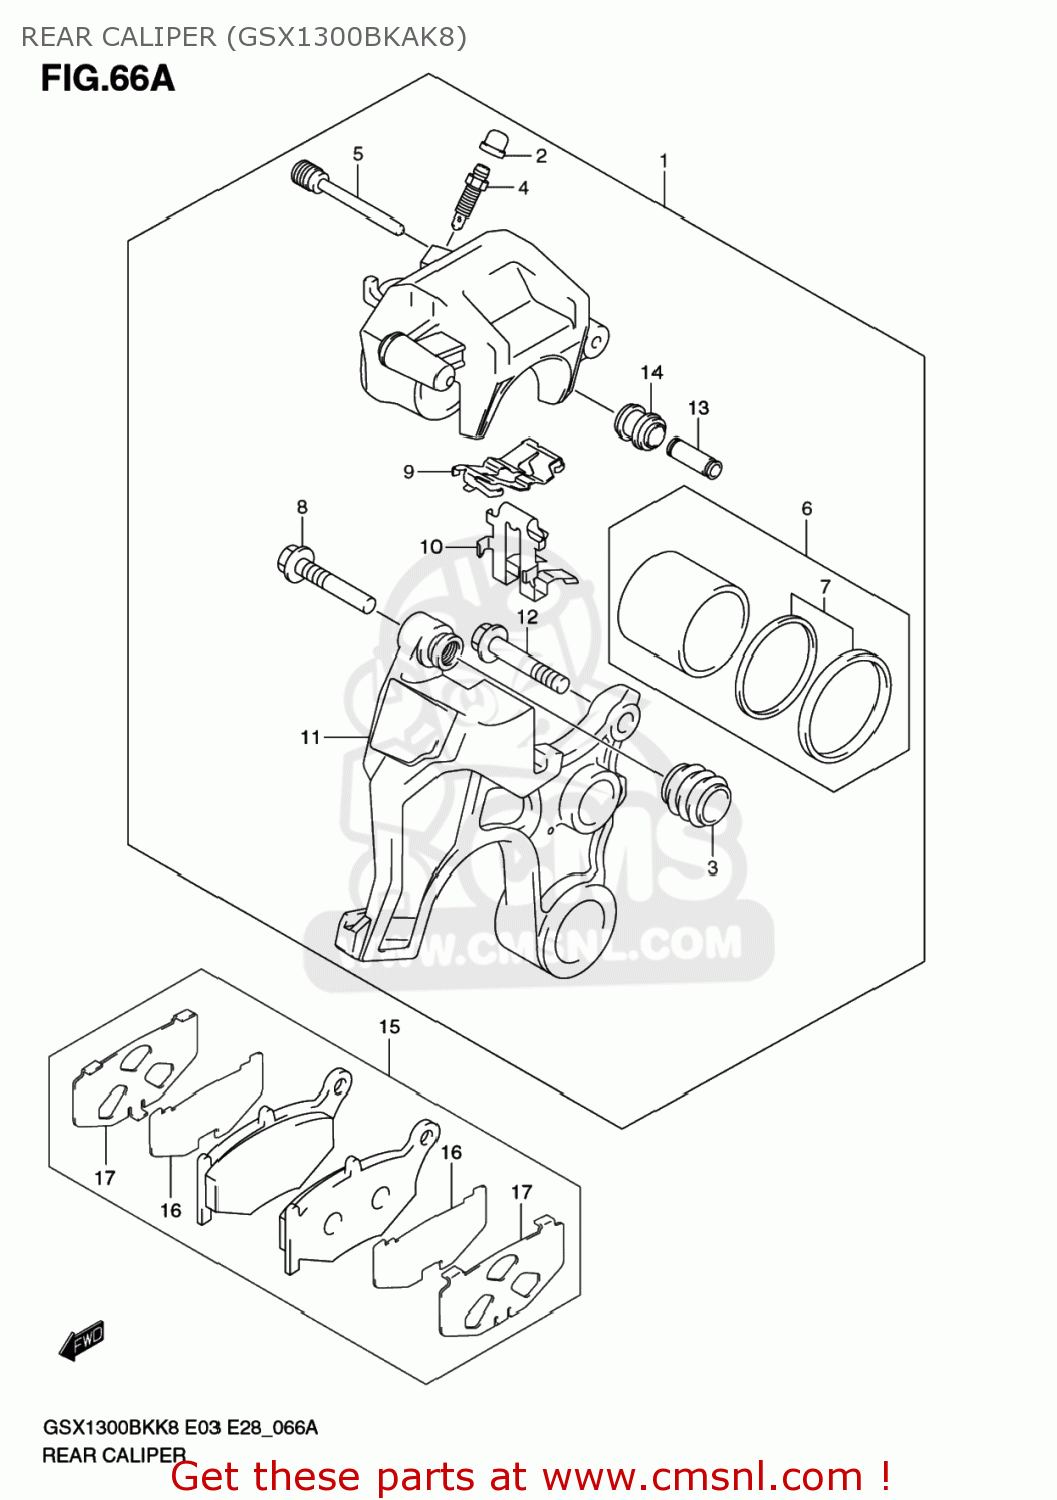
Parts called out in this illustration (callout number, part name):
1	CALIPER ASSY,RR
2	CAP,BLEEDER PLUG
3	BOOT,AXLE
4	BLEEDER
5	PIN,PAD
6	PISTON SET
7	SEAL SET,PISTON
8	PIN,BOLT
9	SPRING,PAD
10	RETAINER
11	BRACKET
12	BOLT
13	SLEEVE
14	BOOT,SLEEVE
15	PAD & SHIM SET (NAS)
16	INSULATOR
17	SHIM
